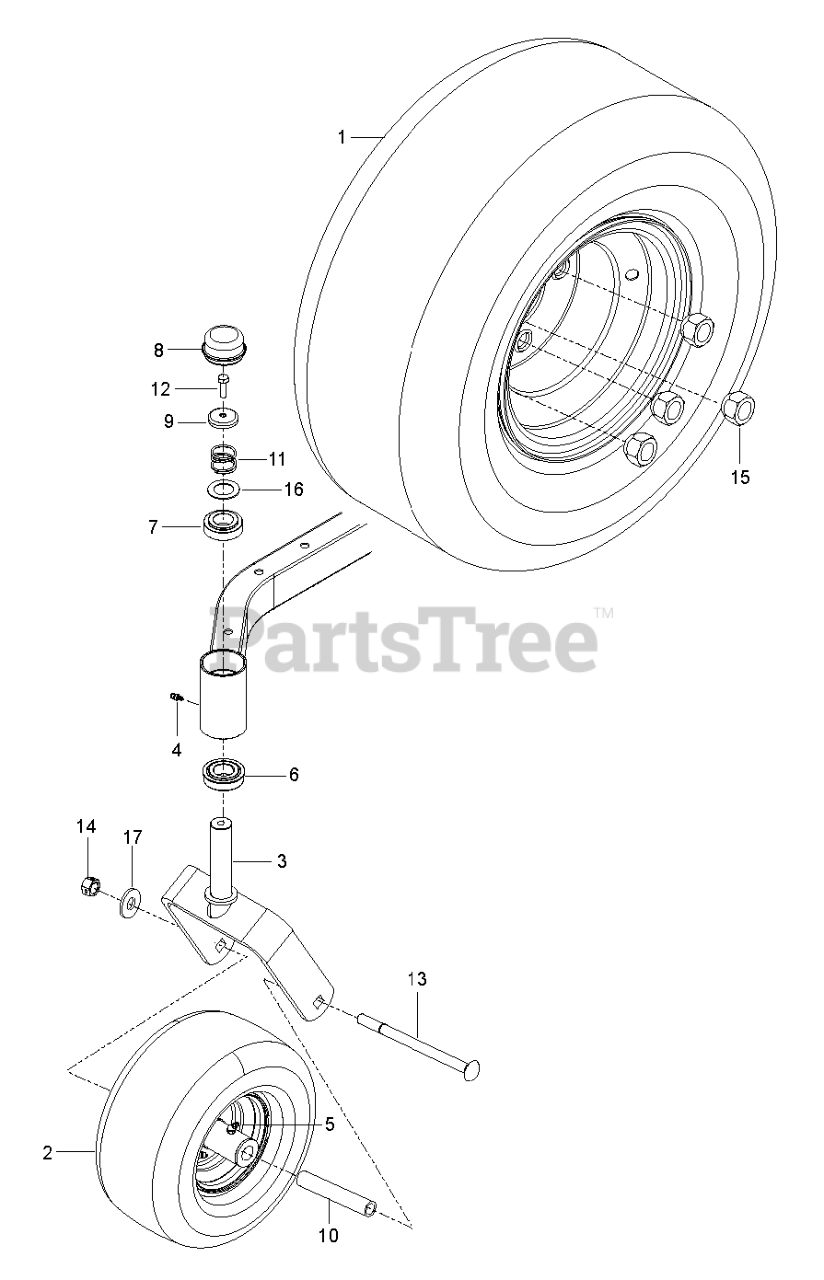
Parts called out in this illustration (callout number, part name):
1	WHEEL CARLSTAR 18X9.5-8" SILVE
2	WHEEL ASSY, WIDE, RZ
3	YOKE.PNT.CASTER.ORG
4	ZERK, 3/16, DRIVE IN
5	ZERK
6	BEARING FLANGED
7	BUSHING, CASTER
10	SPACER.PIVOT
13	Hardware
14	Nuts
